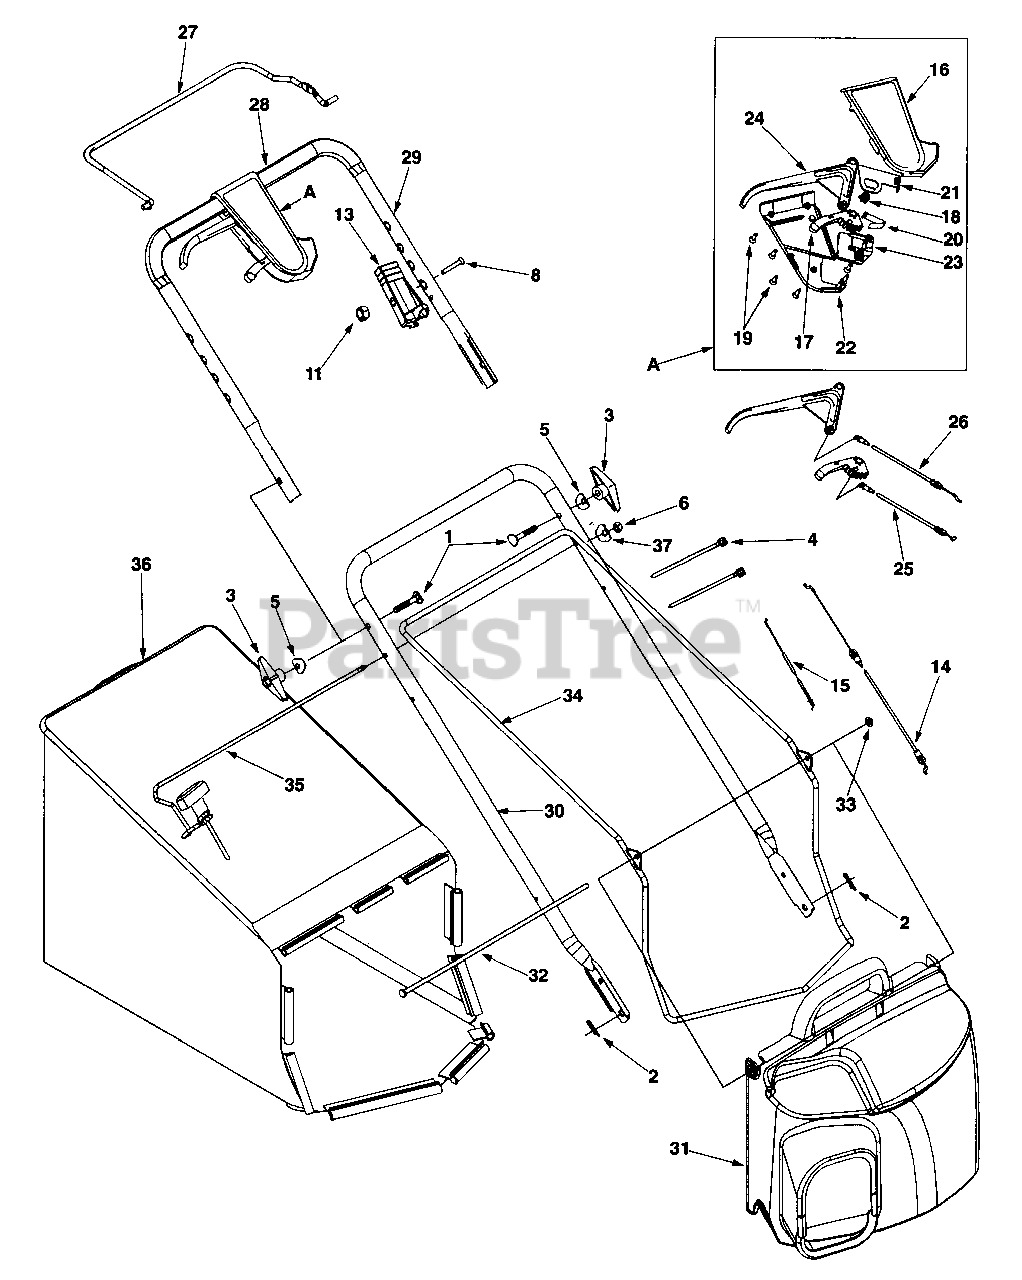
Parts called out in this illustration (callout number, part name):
1	Bolt Cur. Carr. 5/16-18 x 2.0
2	Cotter Pin .072 x 1.12 Lg.
3	Knob Ass'y Wingnut 5/16-18
4	Strap 4.3 Lg.
5	Wash. Sad. .320 ID x.830 OD
6	Hex Nut 5/16
8	Oval C-Sunk Screw
11	Nut 1/4-20 Top locknut Insert
13	Control Housing
14	Control Cable 47" Lg.
16	Upper Control Housing
17	6 Speed Shift Lever
18	Gear Insert
19	C Sunk Tap Screw #10 x .75 L
20	Shift Lever Spring
21	6 Spd. Rack Cable Brkt.
22	Lower Control Housing
23	Cable Mounting Cap
24	Control Lever
25	6 Spd. Cable
26	S.P. Cable
28	Foam Grip
31	Grassbag Cover w/Label
32	Pivot Rod
33	Cap Nut
36	Grassbag
37	Saddle Washer
